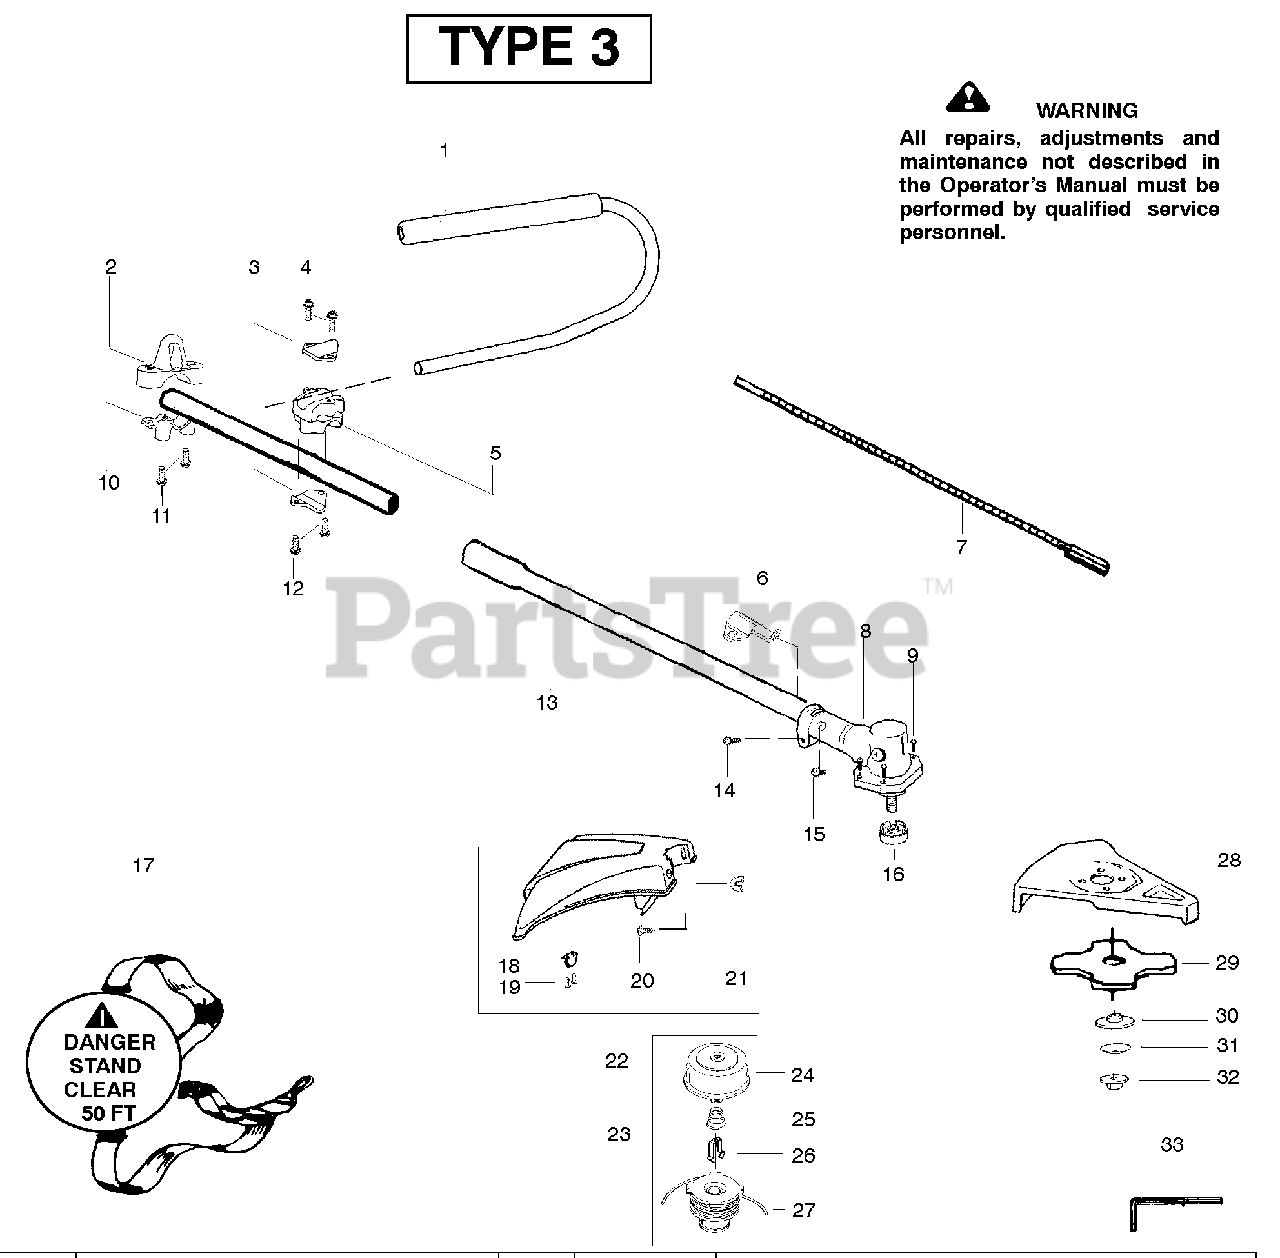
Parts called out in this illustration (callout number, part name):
1	Kit-Handlebar
2	Clamp-Harness Upper
3	Clamp-Bracket
5	Clamp-Handlebar (7/8")
5	Clamp-Handlebar (1")
6	Bracket-Shield
7	Flexshaft-Split boom
10	Clamp-Harness Lower
13	Assy.-Driveshaft
15	Screw-Alignment
16	Dust cup - Blade
17	Assy-Shoulder Strap
19	Screw
21	Wingnut
22	Kit-Shield
23	Accy-Cutting Head
27	Accy-Spool
28	Kit-Blade Shield
29	Accy.-Weed Blade (8")
30	Washer-Blade Retaining
31	Washer-Belleville
33	Wrench-Hex (5/32")
